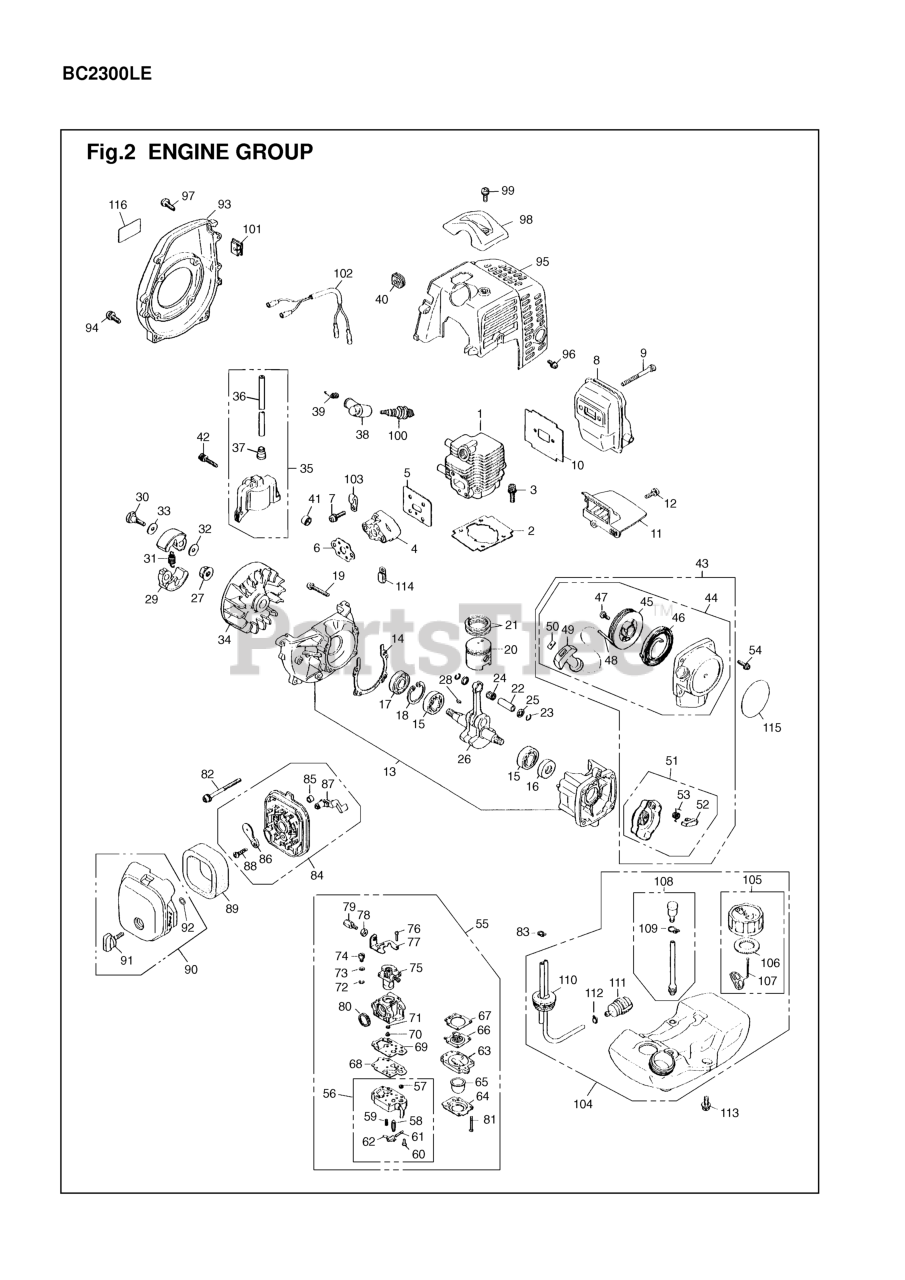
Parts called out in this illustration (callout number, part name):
1	CYLINDER
3	BOLT, M5 X 22
7	SCREW, M5X20 (RPLS.1400-75510)
9	BOLT, M5 x 50
10	GASKET, MUFFLER
13	CRANKCASE
15	BEARING
16	SEAL, OIL (RPLS 1100-21210)
17	SEAL
18	RING
19	BOLT, M5 X 30
20	PISTON (REPLACES 1140-41110)
21	RING, PISTON (RPLS 1850-41210)
22	PIN, PISTON 5x8x26
23	RING
25	WASHER
26	CRANKSHAFT (RPLS 1850-42000)
27	NUT
28	KEY
29	SHOE, CLUTCH (RPLS -51110)
30	BOLT
31	SPRING, CLUTCH (RPLS-51220)
32	WASHER
33	WASHER
34	ROTOR
35	COIL ASSY (RPLS 5500-71200)
36	CORD
37	CAP
39	SPRING
40	GROMMET
41	SPACER
42	BOLT
44	RECOIL ASSEMBLY
45	REEL
46	SPRING
47	SCREW (RPLS -75150)
49	KNOB
50	PLATE, STOPPER
51	PULLEY ASSY (RPLS -75210)
52	RATCHET (RPLS 1850-75220)
53	SPRING, RETURN
55	CARBURETOR (RPLS -81001)
56	BODY ASSY
58	VALVE
59	SPRING, METERING LEVER
60	SCREW, METERING LEVER PIN
61	PIN
62	LEVER
63	BODY
64	COVER
65	PUMP
66	DIAPHRAGM (USE 4810-81260)
67	GASKET, DIAPHRAGM
68	DIAPHRAGM
69	GASKET, PUMP
70	JET
71	O-RING
72	RING
73	WASHER
74	SWIVEL
75	VALVE, THROTTLE (RPLS. -81152)
76	SCREW
78	NUT
79	SCREW
80	RING, PACKING
81	SCREW
83	CLIP
84	BODY-A (RPLS -82101)
85	SLEEVE
86	PLATE, CHOKE (RPLS-82130)
87	LEVER
88	SCREW
89	ELEMENT
91	KNOB
92	RING
93	COVER, FAN (RPLS-31110)
96	SCREW, M5 x 12
97	SCREW, HOUSING
98	GUARD, PLUG
102	CORD COMPLETE
103	CLAMP
104	TANK ASSY
105	CAP ASSY
106	PACKING
107	STOPPER (RPLS 3317-57240)
108	BREATHER ASSY (RPLS -85601)
109	CLIP
110	PIPE COMPLETE
111	FILTER (RPLS 1850-85300)
112	CLIP
113	SCREW
114	CLAMP
115	LABEL, RECOIL
116	LABEL, COVER
